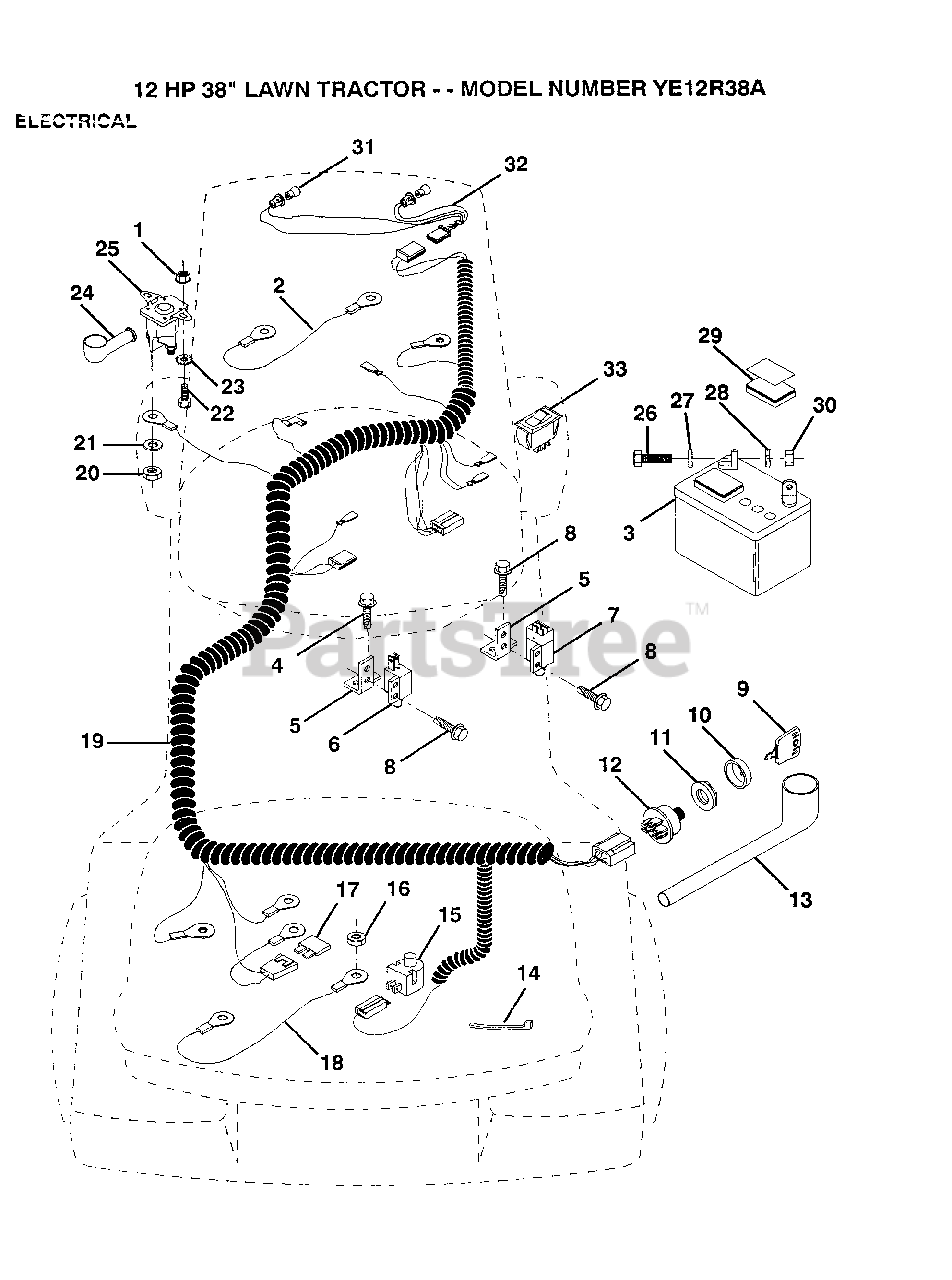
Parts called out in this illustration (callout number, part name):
1	NUT
2	CABLE ASM.
4	SCREW
5	BRACKET LT
6	SWITCH-INTER. GT
7	SWITCH INTERLOCKT
8	SCREW
9	KEY
11	NUT IGNITION
13	COVER IGNITION SW
14	WIRE TIE
15	SWITCH SEAT
17	FUSE HYT
18	CABLE ASSY
20	NUT
22	BOLT
26	BOLT LT
27	WASHER
28	LOCKWASHER
29	"CAP,BATTERY "
33	SWITCH LT
